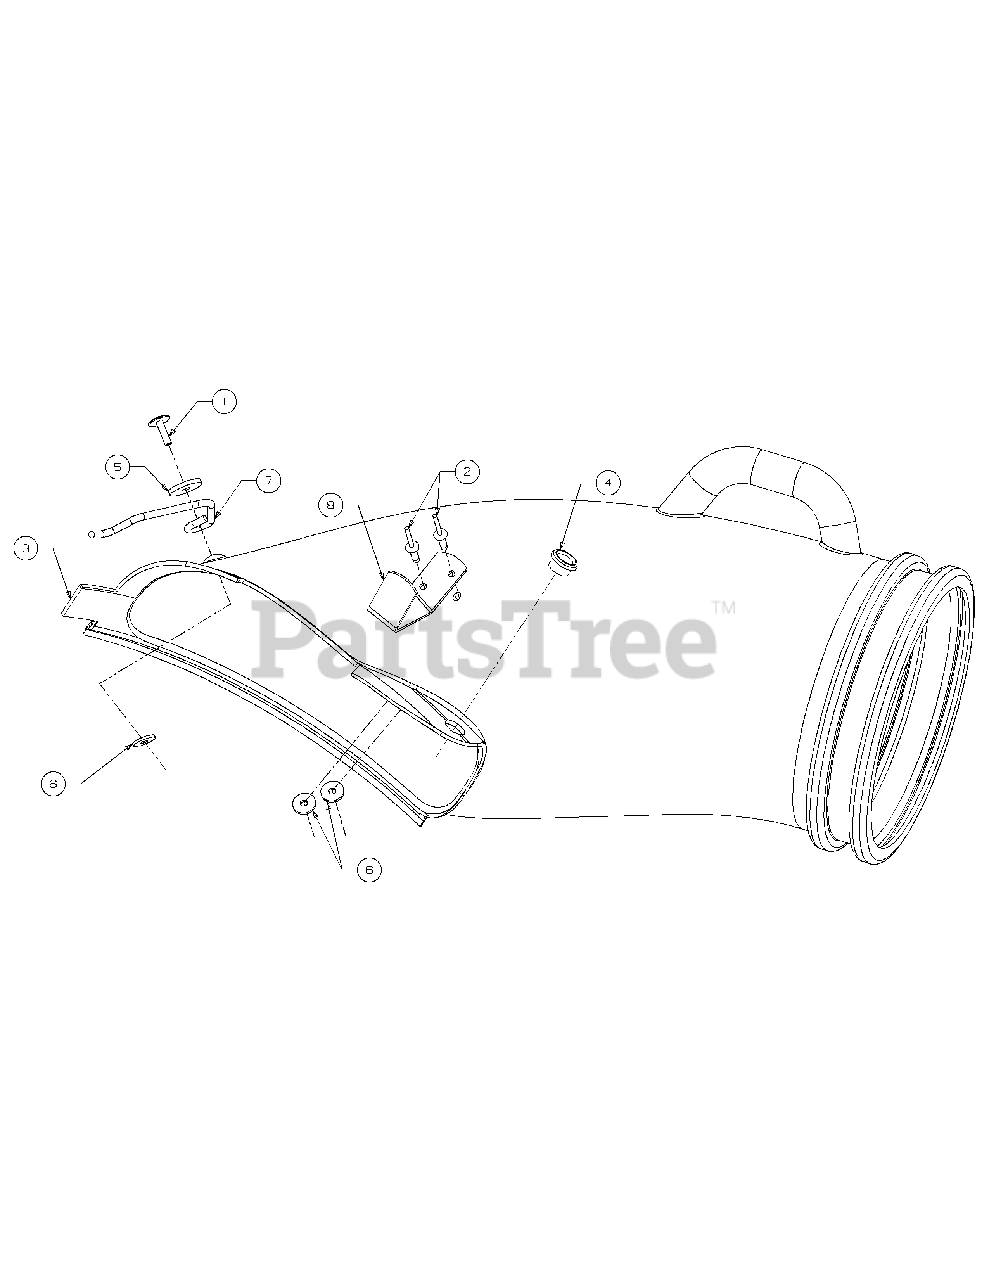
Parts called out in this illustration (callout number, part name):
1	Rivet, Pop .188 Dia
2	Rivet, Pop .187 Dia
3	Chute Assembly, Elbow
5	Washer, Flat .265
6	Washer, Flat .194
